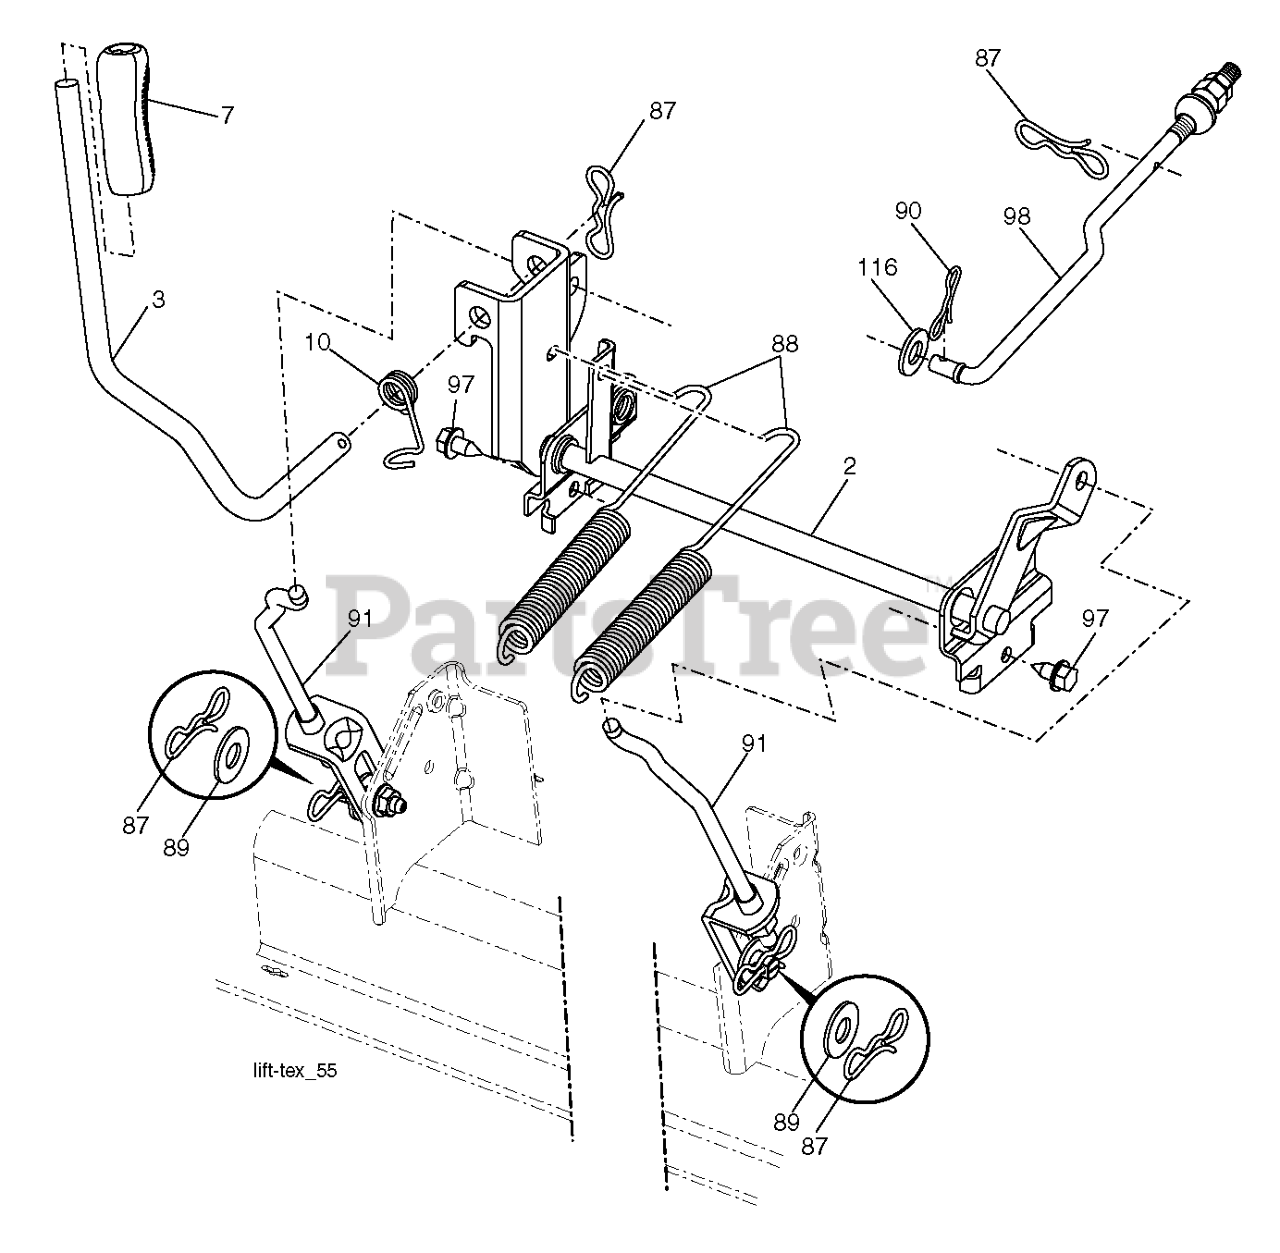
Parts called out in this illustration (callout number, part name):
2	SHAFT.ASM.CROSS.LIFT
3	LEVER.LIFT.HANDLE.LT
7	GRIP.HANDLE.LIFT.PVC.BLACK
10	SPRING.TORSION.LIFT.HANDLE
87	PIN.COTTER.7/16.BOW TI.
88	SPRING.LIFT.ASSIST
89	WASHER.CLEAR.ZINC
90	PIN.COTTER.5/16.BOW TI
91	LINK.ASM.LIFT.REAR
97	SCREW, 3/8-16X3/4
98	LINK.ASM.SUSP.FRONT.MWR.10.5
116	WASHER
